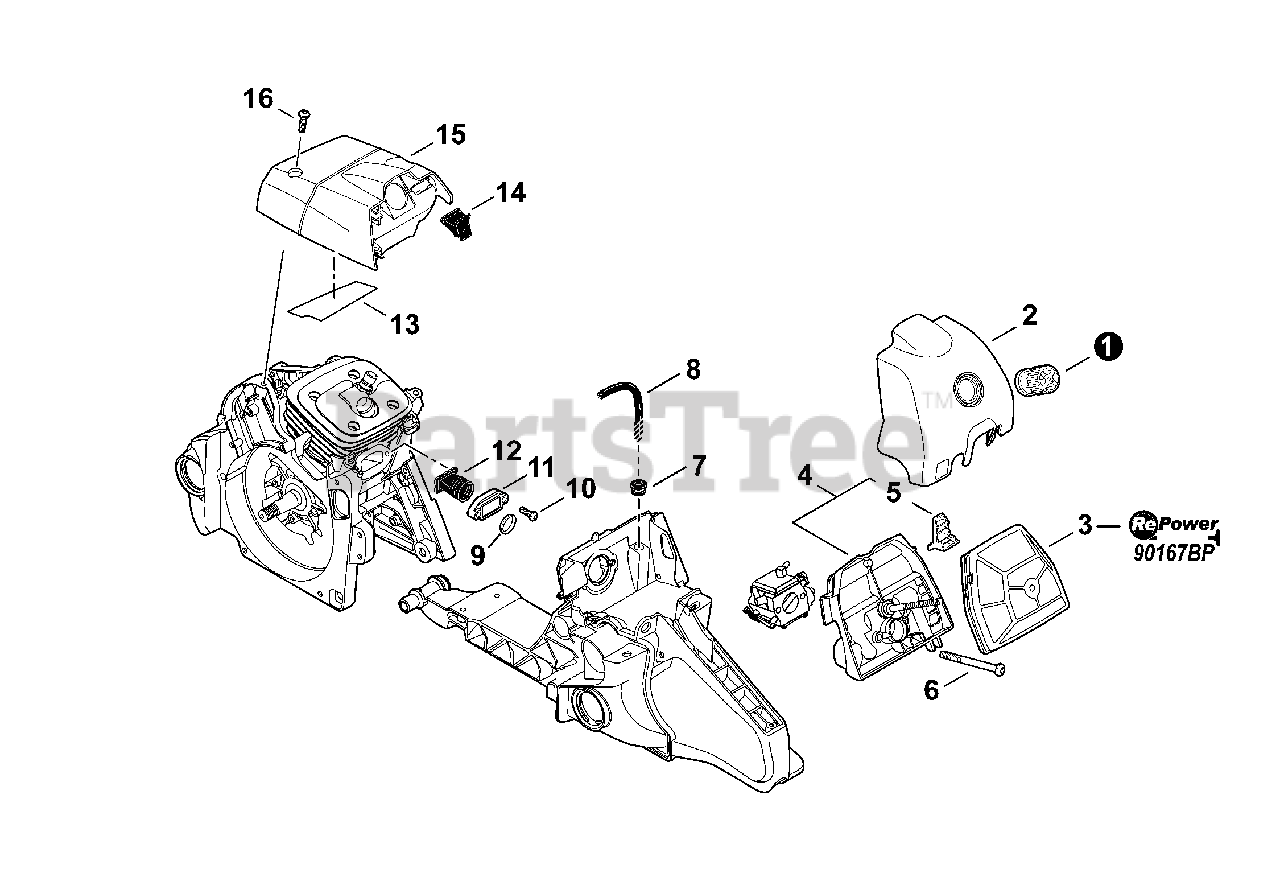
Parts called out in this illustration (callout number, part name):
1	KNOB, AIR CLEANER
2	COVER, AIR CLEANER
3	FILTER, AIR
4	AIR CLEANER CASE KIT
5	SHUTTER, AIR
6	SCREW, TAPPING - 5×50
7	GROMMET
8	PIPE, IMPULSE
10	SCREW - 5×16
11	ADAPTER
12	BELLOWS
13	DEFLECTOR, HEAT
14	DUCT, INTAKE
15	COVER, ENGINE
16	SCREW - 5×16
